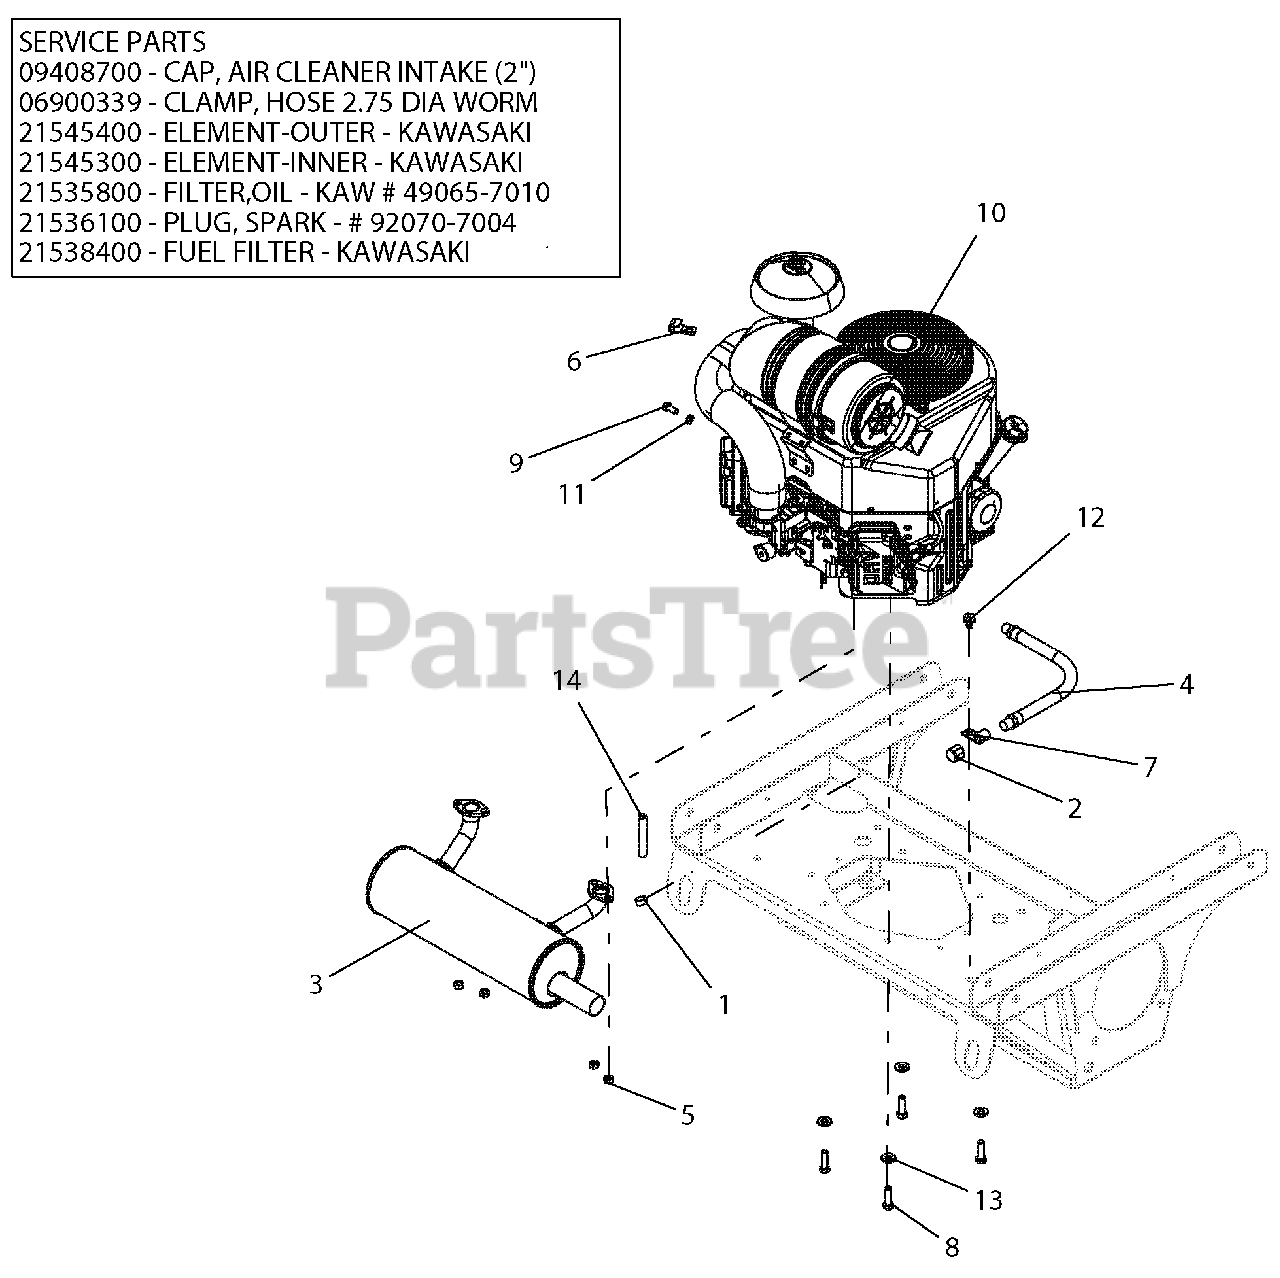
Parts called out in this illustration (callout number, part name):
1	CLAMP, FUEL LINE
2	PIPE, CAP 3/8 NPT FEMALE
3	MUFFLER, KAWASAKI FX24/26 HP
4	HOSE, HYD .38-11-OK M6N0-M6N0
5	NUT-LK-TOP M8-1.25 YWZC
6	CLAMP, J
8	BLT-HEX .38-16X1.25 GR5 YWZC NYTORQ
9	@BLT-HEX M8-1.25X20 YWZC
10	ENGINE, KAWASAKI FX730
11	WSHR-LK .31X.078 REG YWZC
12	SCR-TAP .38-16X.50 HWH TR YWZ
13	WSHR, 3/8" SPRING DISC
14	.25 LOW-PERM GAS HOSE 3.00" LG - VALVE TO KAW FX730
